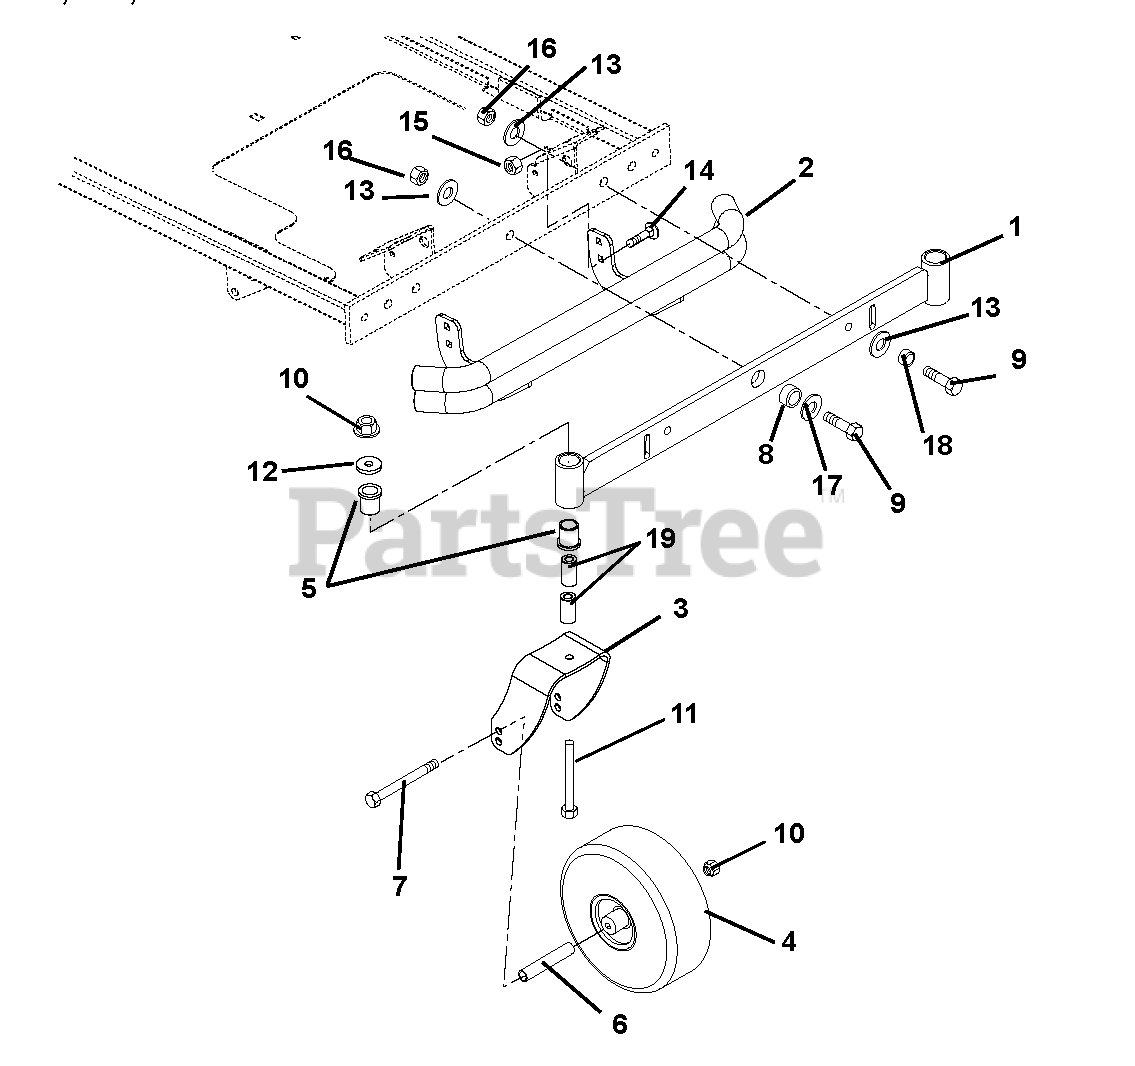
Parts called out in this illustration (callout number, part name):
1	Weldment, Front Axle
2	Bumper, Zoom
3	Fork, Caster
4	Assembly, Tire 4 x 11- 4 Ply
5	Bushing, Flange 1.00 x 1.25 x 1.50 x 1.50
6	Spacer, Rolled Wheel
7	Bolt, Hex .50-13 x 6.50 Grade 5
8	Bushing, Axle Pivot
9	Bolt-Hex .62-11X2.25 Grade 8
10	Nut, Locking Top Flange .50-13
11	Bolt, Hex .50-13 x 5.00 Grade 5
12	Washer, Flat Steel .511 x 1.441 x .125
13	Washer, Flat .64 x 1.81 x .25
14	Bolt, Round Head Square Neck .38-16 x 1.00 Grade 5
15	Nut .38-16 Flange Nyloc
16	Nut, Locking Nylon .625-11
17	Washer, Flat Steel .688 x 1.75 x .134
18	Spacer, .750 D x .558 Long
19	Spacer, Caster
